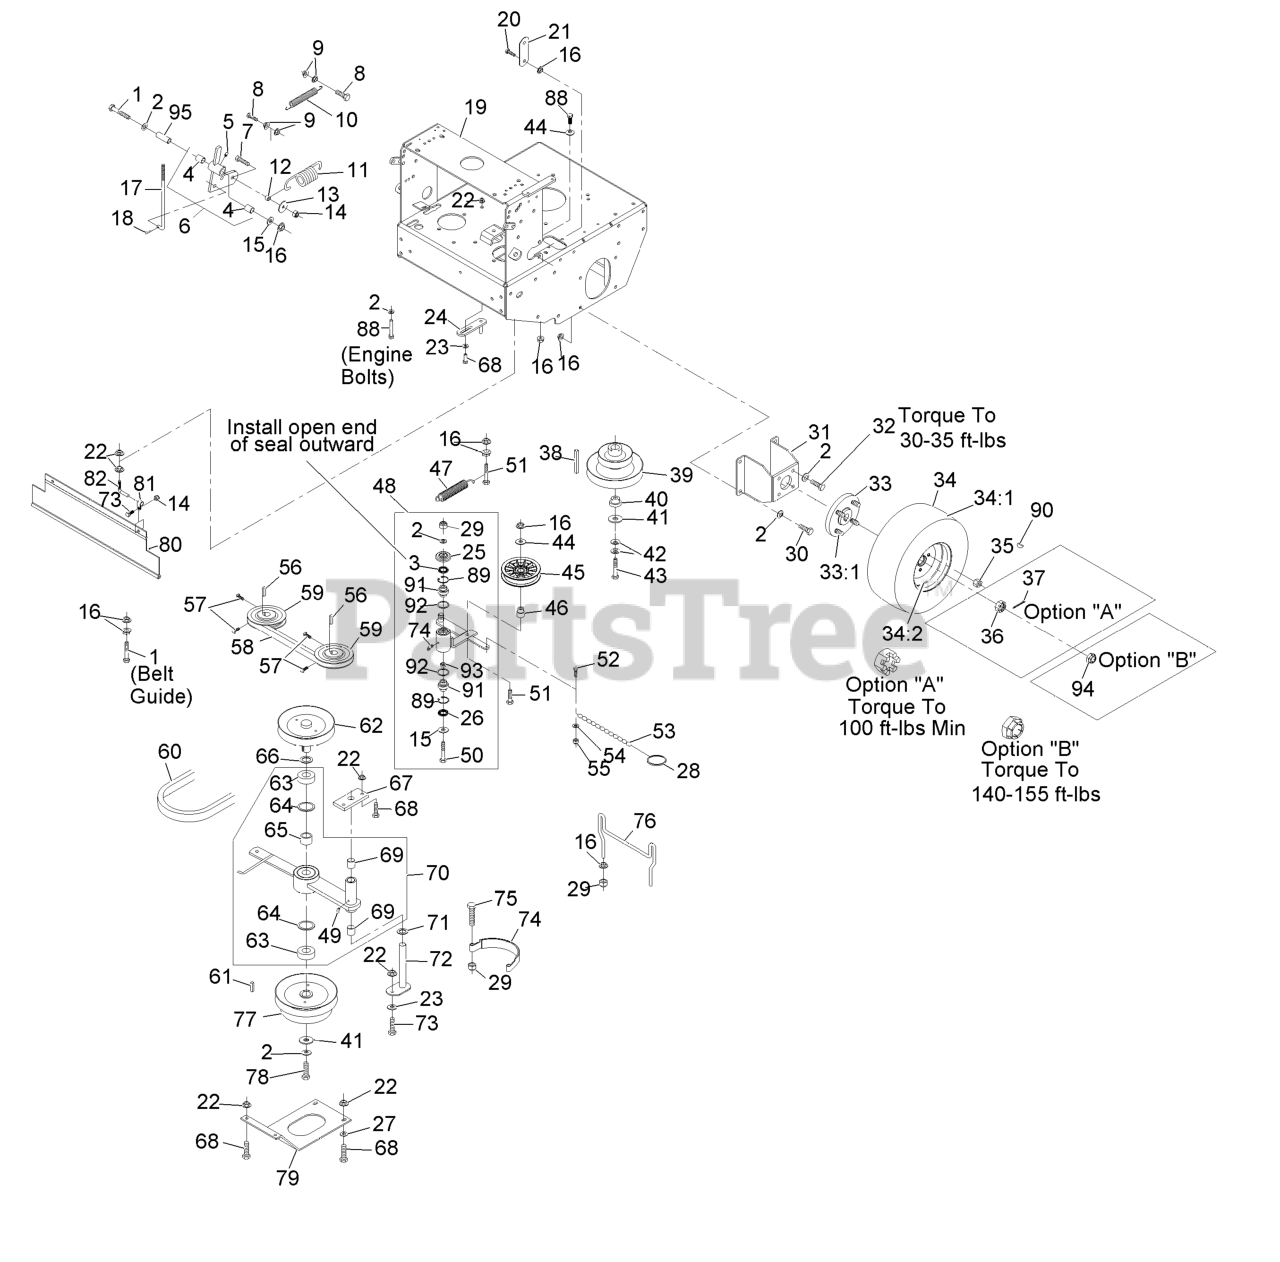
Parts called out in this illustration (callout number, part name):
1	SCREW-HH
2	WASHER-BELLEVILLE
3	SEAL-LIP, SINGLE
4	SLEEVE-BEARING
5	FITTING-GREASE
6	ASM,PIVOT W/BUSHINGS
7	SCREW-HH
8	SCREW-HH
10	SPRING,EXTENSION
11	SPRING,EXTENSION
12	SPACER,CLUTCH ANCHOR
14	NUT-LOCK, NI
15	WASHER-FLAT
16	NUT-HHF, WHIZ
17	LINKAGE,LOWER
18	PIN-COTTER
19	KIT,TTHP ENG DECK
20	SCREW-HH
21	ARM-LIFT, DECK
23	WASHER-SPRING
24	GUIDE-BELT
25	GUARD-TOP
26	SEAL-LIP, DOUBLE
27	WASHER-FLAT
28	RING-SPLIT
29	NUT-LOCK, NI
30	SCREW-HH
31	WLD,MOTOR MOUNT 48&52
32	SCREW-HH
33:1	STUD-WHEEL
34	WHEEL AND TIRE ASM
34:1	TIRE-TURFMASTER
34:2	RIM-WHEEL
35	NUT-LUG
36	NUT-HEX, SLOTTED
37	PIN-COTTER
38	KEY,MACH 1/4X1/4X2-5/8
39	SHEAVE, DRIVE
40	BUSHING,CLUTCH KEEPER
42	WASHER-SPRING
43	SCREW-HH
44	WASHER-FLAT
45	PULLEY-IDLER, FLAT
46	BUSHING-IDLER
48	KIT,PUMP IDLER ARM TTHP
49	FITTING-GREASE
50	SCREW-HH
51	SCREW-HH
52	SCREW-HSH
53	CHAIN-LINK, TWIST
54	WASHER-FLAT
55	NUT-LOCK, NI
57	SCREW-SET
58	BELT,COG A 50.55
59	SHEAVE ASM
60	BELT,B-38.0
62	SHEAVE, W/ SHAFT
63	BEARING,CLUTCH SHAFT
64	RING-SNAP
65	SPACER,CLUTCH BEARING
66	WASHER-SPACER
67	PLATE-CLUTCH PIVOT
68	SCREW-HH
69	SLEEVE,BEARING
70	ASM,CLUTCH ARM W/BEARING
71	WASHER-SPACER
72	WLD,PIN PIVOT
73	SCREW-HH
74	BAND,BRAKE BLADE
75	SCREW-HH
76	GUIDE,BELT (PLTD)
77	SHEAVE,6.75 W/DRUM
78	SCRW,CAP HH
79	PLATE-GUARD
80	SHIELD-DRAG
81	CLIP-LOOM
82	MOUNT,DRAG SHIELD
88	SCREW-HH
89	RING-SNAP
90	KEY-WOODRUFF
91	BEARING-SPHERICAL
94	NUT-LOCK
95	BUSHING
